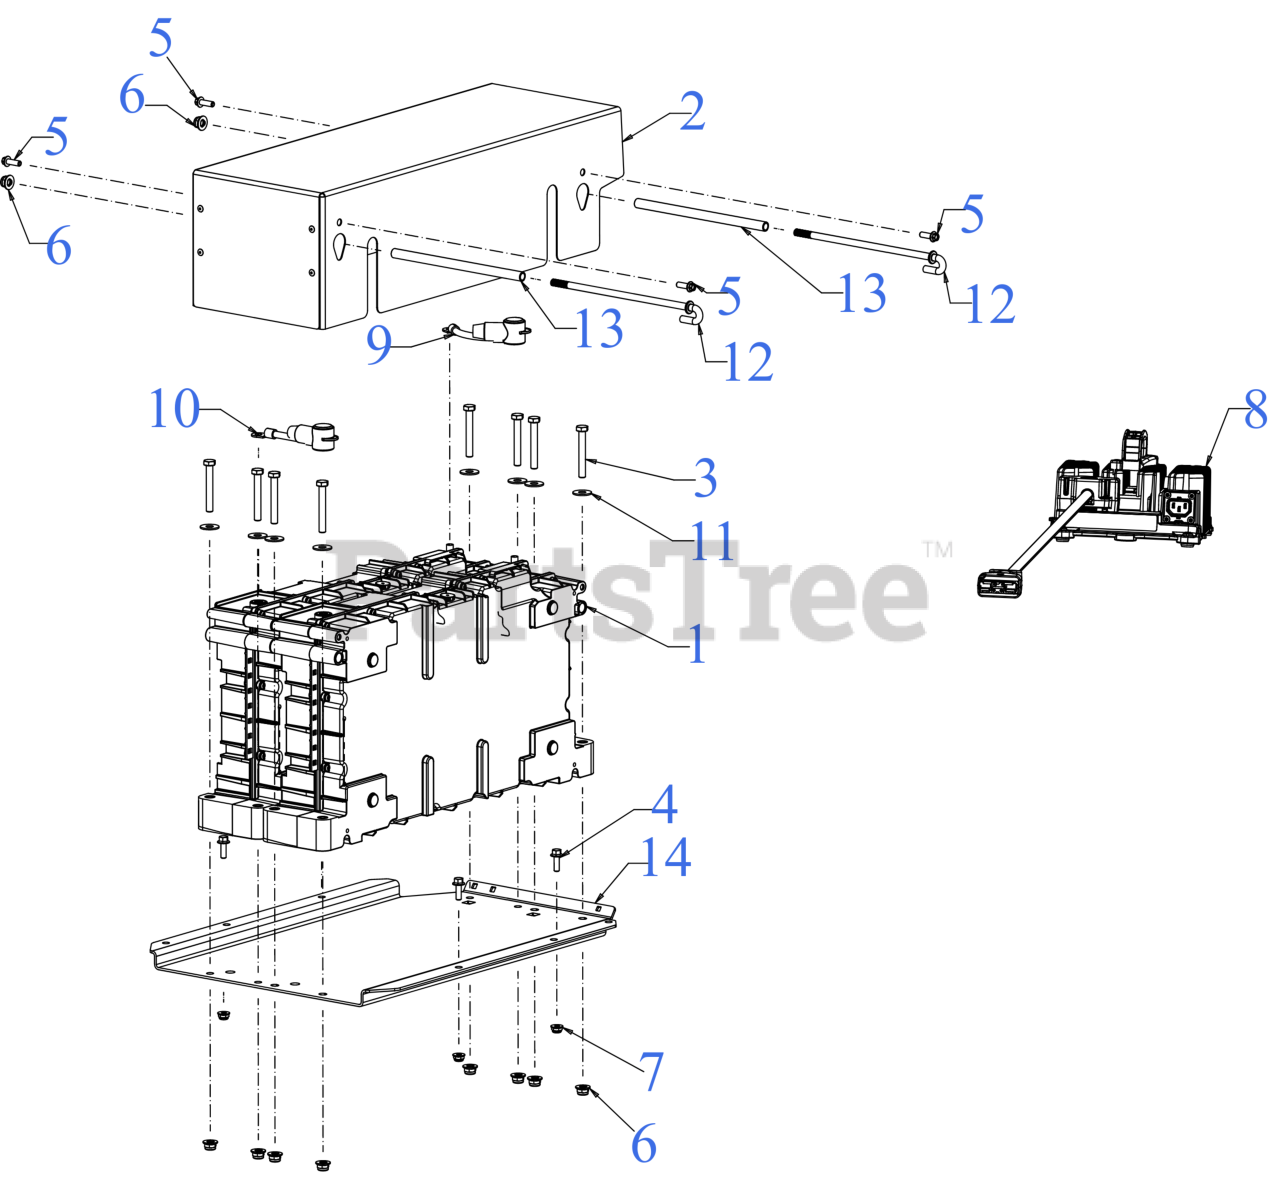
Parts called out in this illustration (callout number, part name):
2	BATTERY COVER
3	HEX SCREW 5/16-18 x 2.25 GR5
4	SCREW 1/4-20 x .75 GR5
5	SCREW 1/4 x .750
6	FLANGE LOCK NUT 5/16-18
7	FLANGE LOCK NUT
8	CHARGER (48V 650W)
9	JUMPER BATTERY HARNESS
10	JUMPER BATTERY HARNESS
11	FLAT WASHER
12	BATTERY ROD
13	SPACER- .322" x .438" x 7.71"
14	BATTERY PLATE BRACKET
